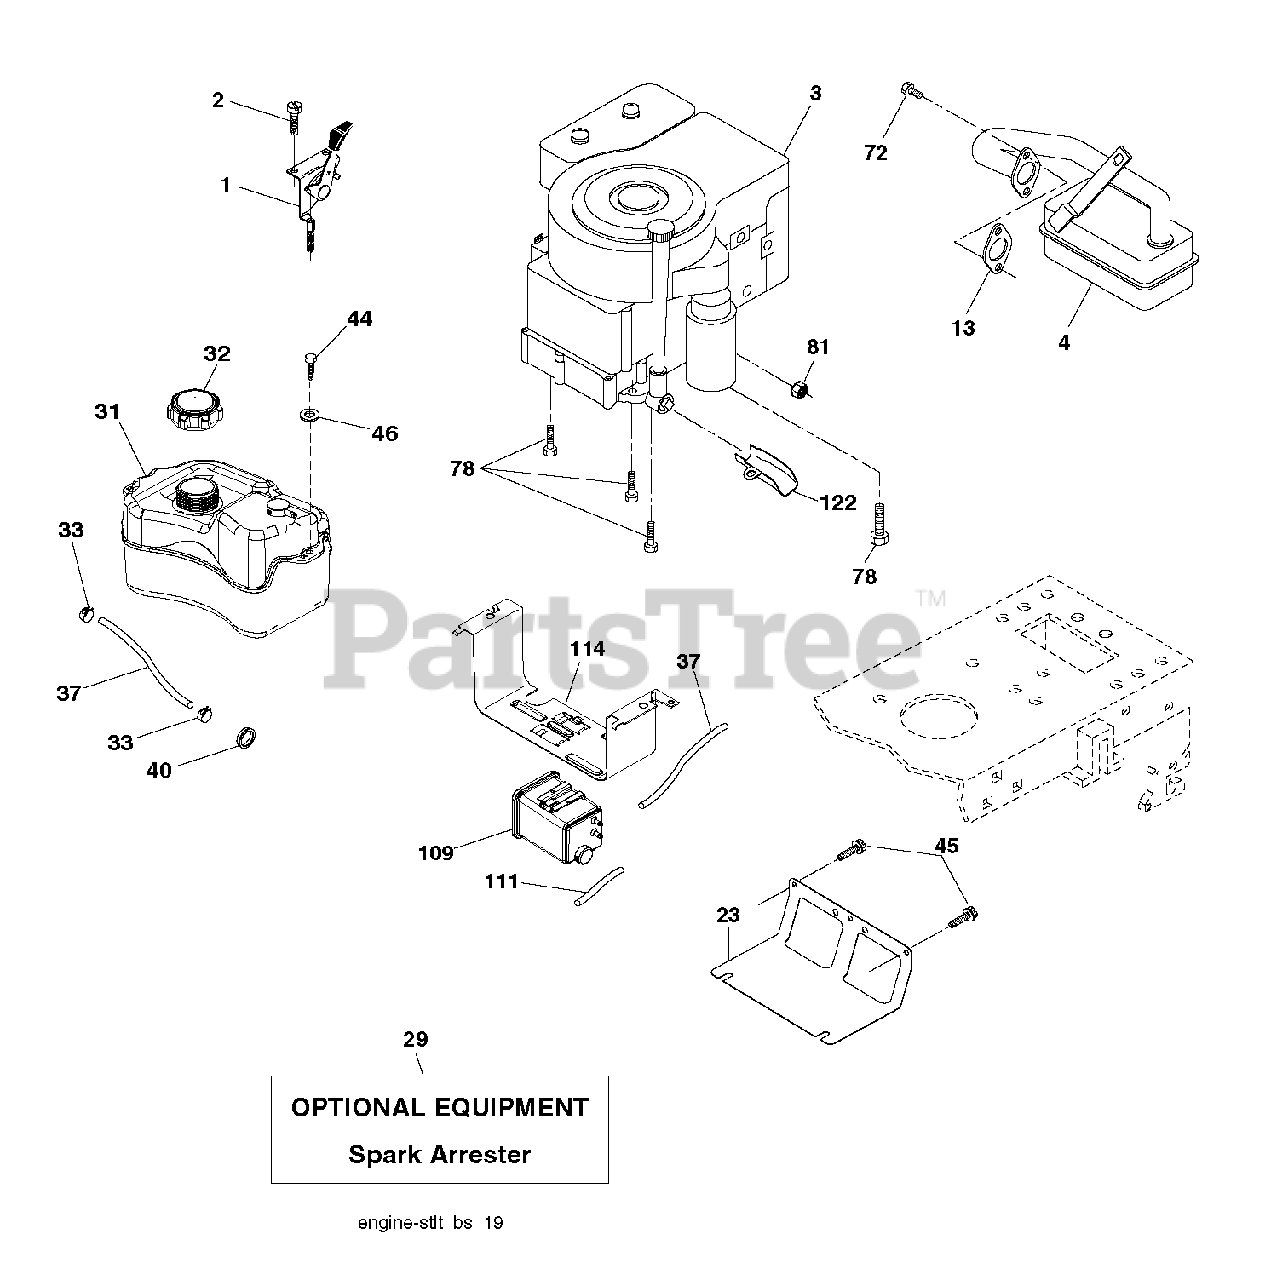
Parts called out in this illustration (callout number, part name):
1	CONTROL.THROTTLE/CHOKE.BLACK
2	SCREW
4	MUFFLER.LT.BRIGGS.14HP.IC/OHV
23	SHIELD.BROWNING.DBR.GUARD
29	KIT.SPARK ARRESTOR(392390 B&S)
31	TANK ASM.FRONT.CARB.1.5GA.E10
32	CAP ASM.FUEL.2.25"FRT.CARB
33	HOSE CLAMP
37	LINE.FUEL.20"FRONT.EMI
40	GROMMET T
44	SCREW HEXWSHR 1/4-20X3/4
45	SCREW, 3/8-16X3/4
72	SCREW.SOCKET HD.5/16-1
78	SCREW.3/8-16
81	NUT
109	CANNISTER, CARBON
111	RP PURGE LINE
122	EXTENSION DRAIN OIL
